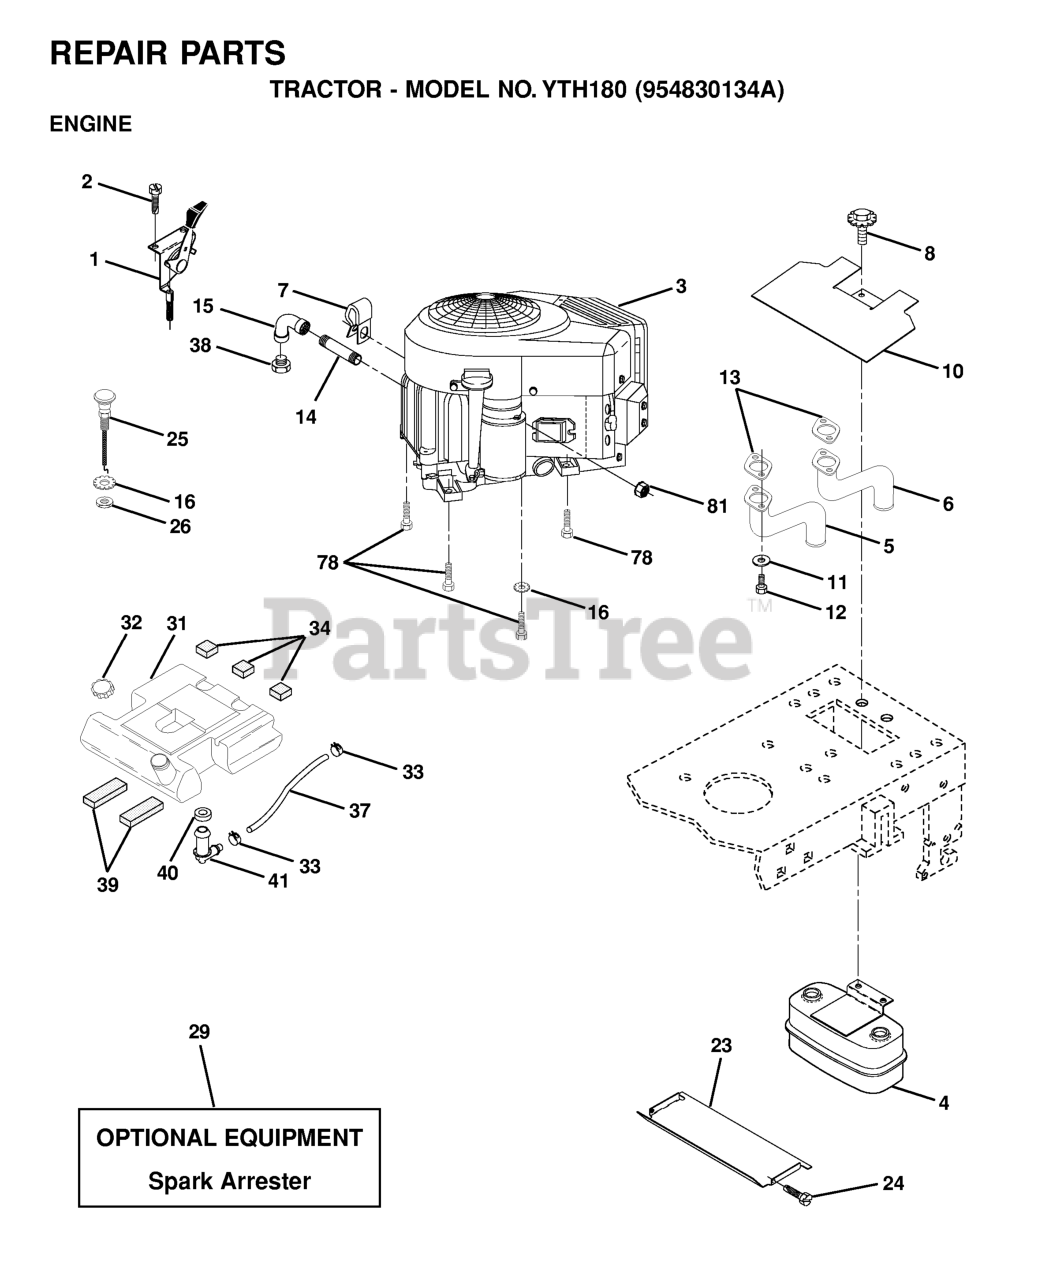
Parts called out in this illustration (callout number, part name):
1	CONTROL THROTTLE 36"
2	SCREW LT
4	MUFFLER.TWIN.CYL.LOW.TONE
5	TUBE ASSY EXH LH
6	TUBE ASSY EXH RH
10	SHIELD HEAT LT
14	Nipple, Pipe 3/8 NPT x 4-1/2
15	ELBOW
16	LOCKWASHER
23	HEAT SHIELD
25	CONTROL, CHOKE
26	NUT
29	KIT.SPARK ARRESTOR 794945 B&S
31	FUEL TANK REAR YT/GT
32	FUEL CAP
33	HOSE CLAMP
34	PAD-SPACER LT
35	SCREW.THDROL.5/16-18X3/4.TTY
36	WASHER
37	HOSE T
39	PAD IDLER TI
40	BUSHING OUTLET T
41	STEM FUEL TANK
78	SCREW
81	NUT FLANGE 1/4-20 STARTER NUT
